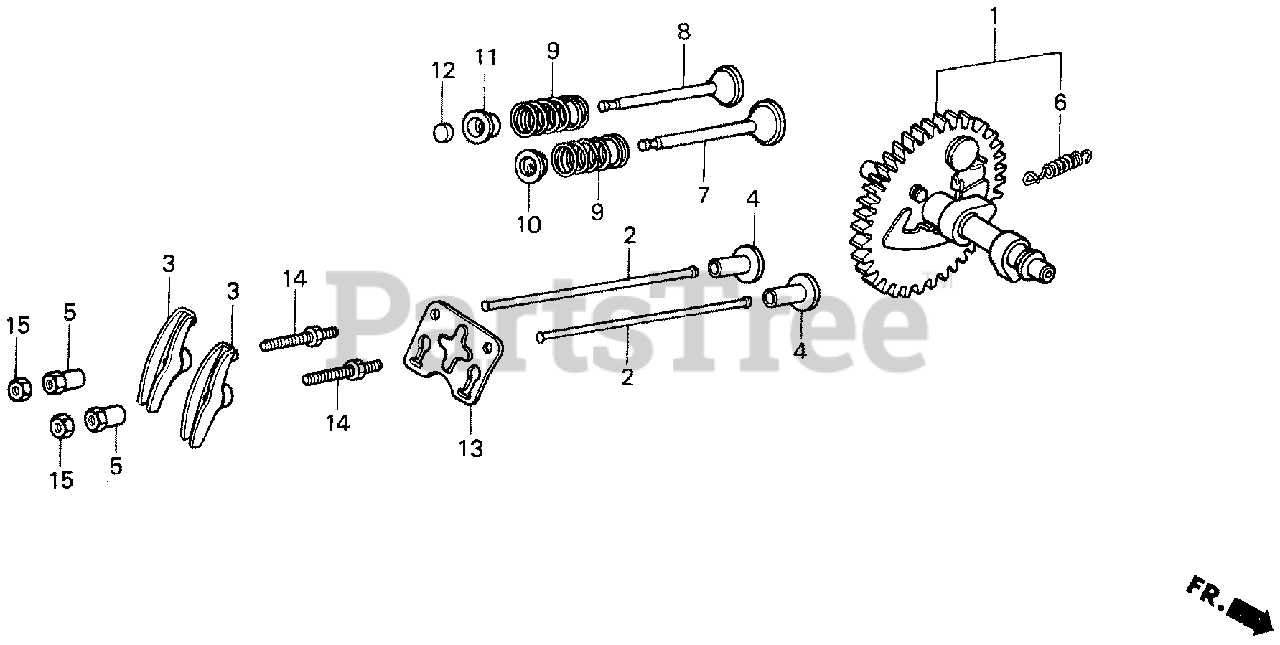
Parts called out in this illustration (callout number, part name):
1	CAMSHAFT ASSY.
2	ROD, PUSH
3	ARM, VALVE ROCKER
4	LIFTER, VALVE
5	PIVOT, ROCKER ARM
6	SPRING, WEIGHT RETURN
7	VALVE, IN.
8	VALVE, EX.
8	VALVE, EX. (STELITE)
9	SPRING, VALVE
10	RETAINER, IN. VALVE SPRING
11	RETAINER, EX. VALVE SPRING
12	ROTATOR, VALVE
13	PLATE, PUSH ROD GUIDE
14	BOLT, PIVOT (8MM)
15	NUT, PIVOT ADJ.
